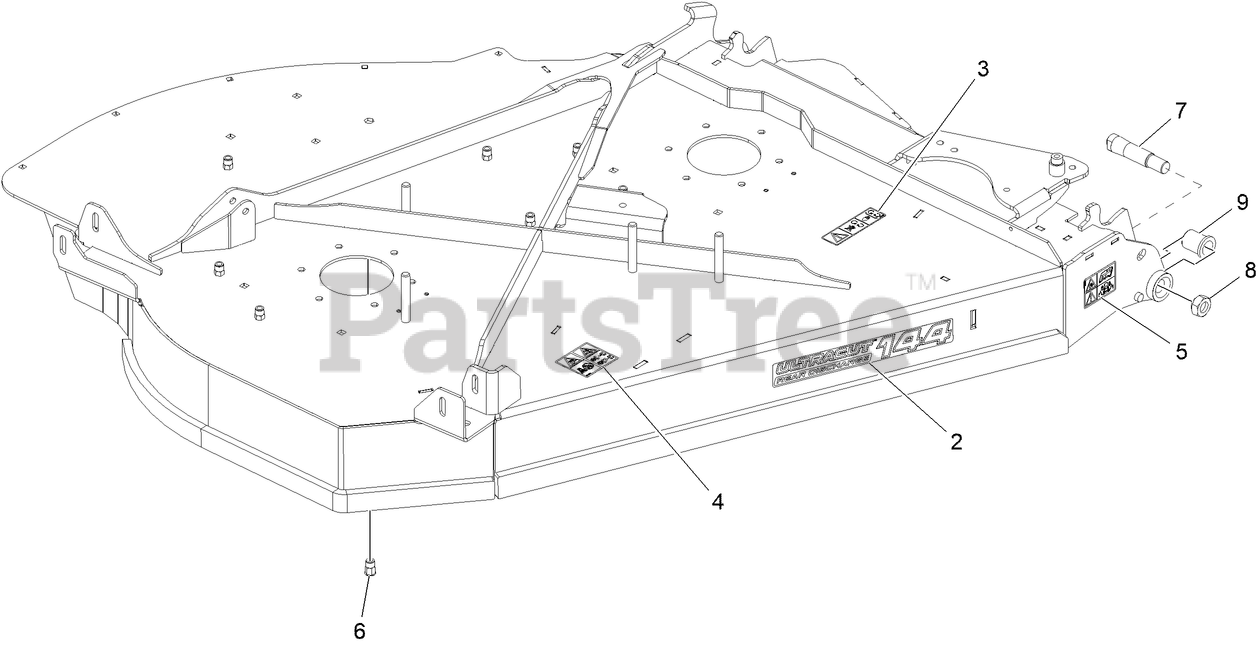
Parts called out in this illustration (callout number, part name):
2	DECAL-ULTRACUT 144
3	DECAL-COVER, MISSING
4	DECAL-DANGER, THROWN OBJECT
5	DECAL-WARNING, PINCH POIN
6	NUT-CLINCH,HEX
7	BOLT-PIVOT PIN
8	NUT-LUG
9	BUSHING-FLANGED
